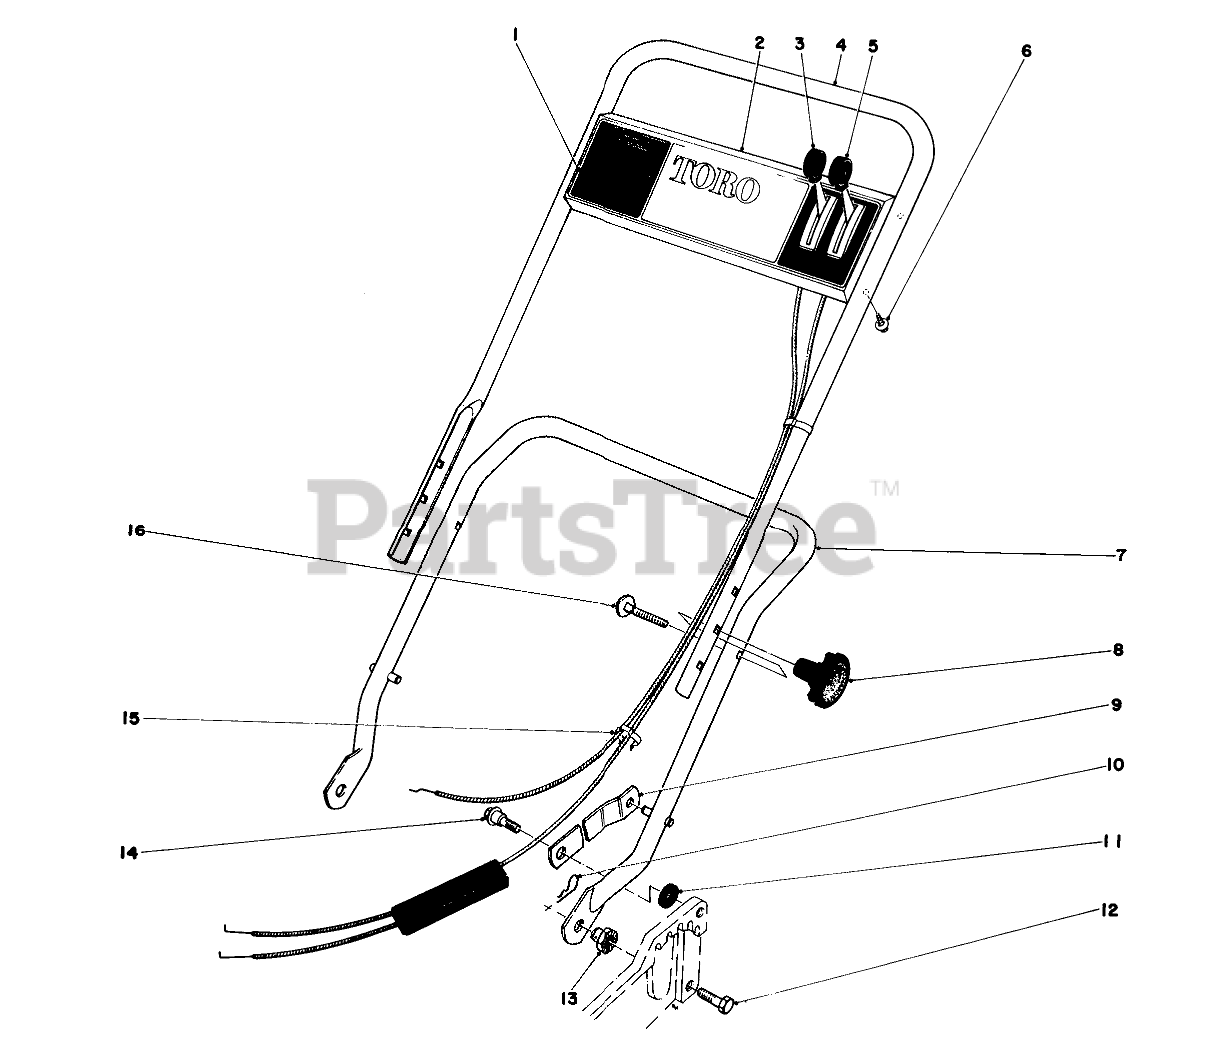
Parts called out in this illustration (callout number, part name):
1	Decal Control Plate
2	Control Plate
3	Throttle Control
4	Upper Handle
5	Traction Control
6	Screw
7	LOWER HANDLE ASM
9	HANDLE LATCH
10	PIN-COTTER, HAIR
11	SPACER
12	SCREW-HH
13	HANDLE PIVOT NUT
14	SCREW-SHOULDER
15	BOWDEN CLIP
16	HANDLE SCREW
